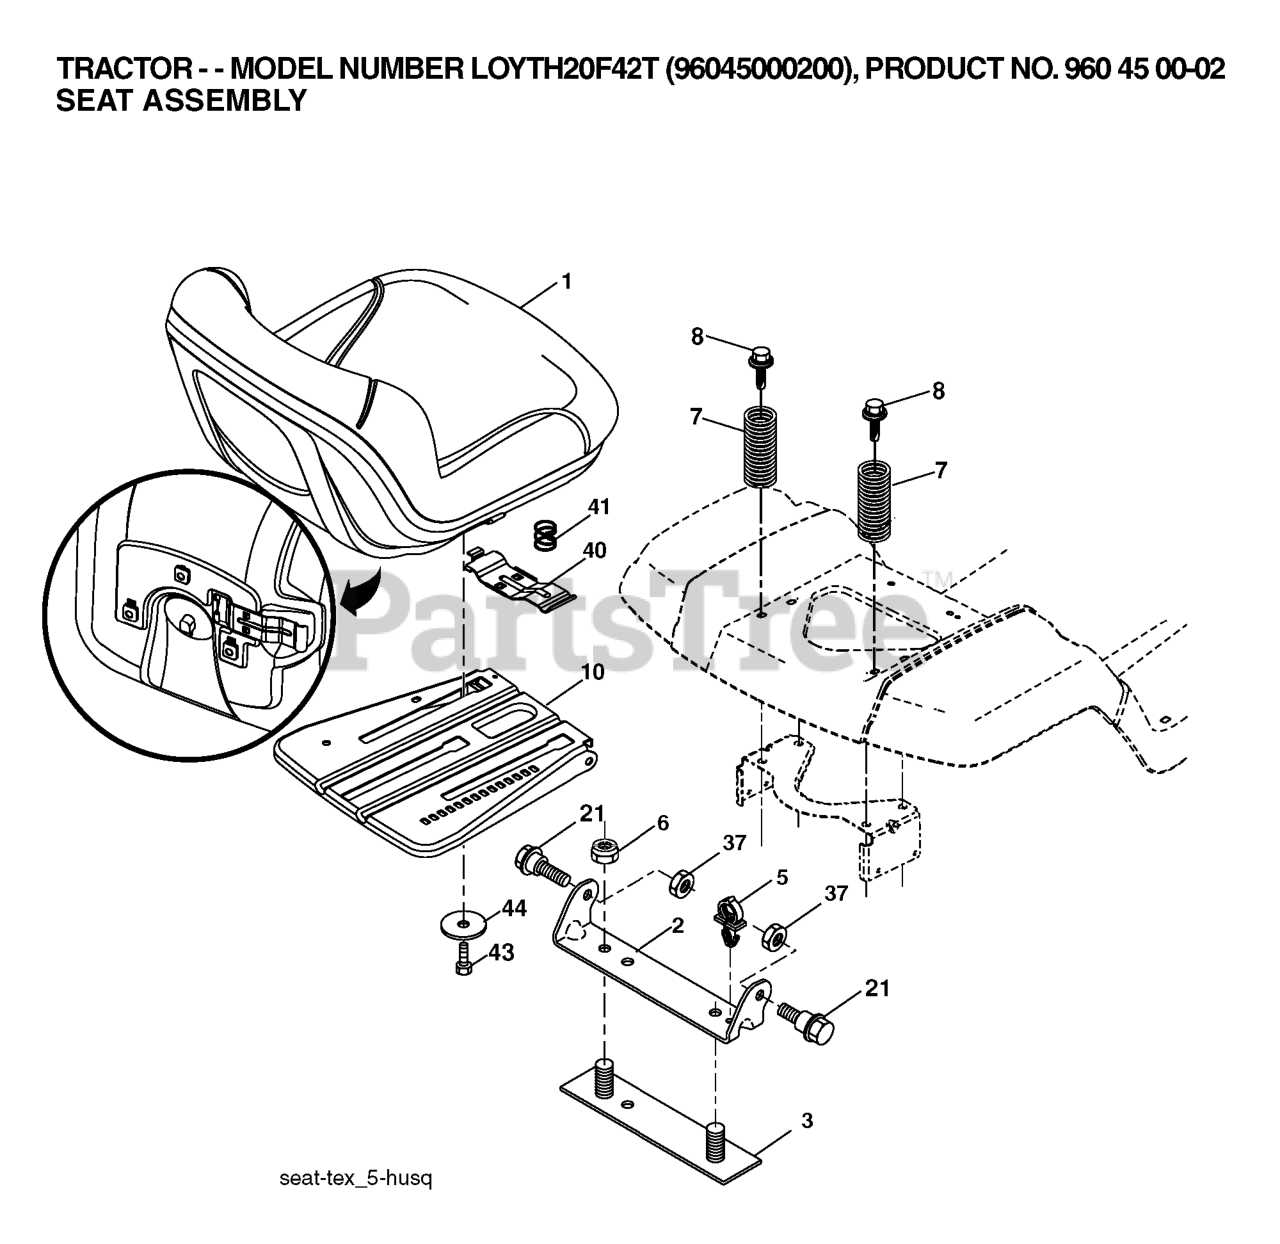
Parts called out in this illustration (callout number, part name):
1	SEAT.TH150.GRY.KB/SL.H
2	BRKT.PIVOT.FENDER
3	STRAP
6	NUT
7	SPRING COMPRESSION
8	BOLT.5/16-18UNCX3/4 W/SEMS.BLK
10	PAN.ASM.SEAT.3PT
21	BOLT.SHOULDER.5/16-18
37	NUT.71038.31-18.HEX.NYLOCK
40	HANDLE.SLIDE.SEAT.TEX.BLACK
41	SPRING.LATCH.SEAT.TEX
44	WASHER 13/32 X 2-3/8 X 12GA
